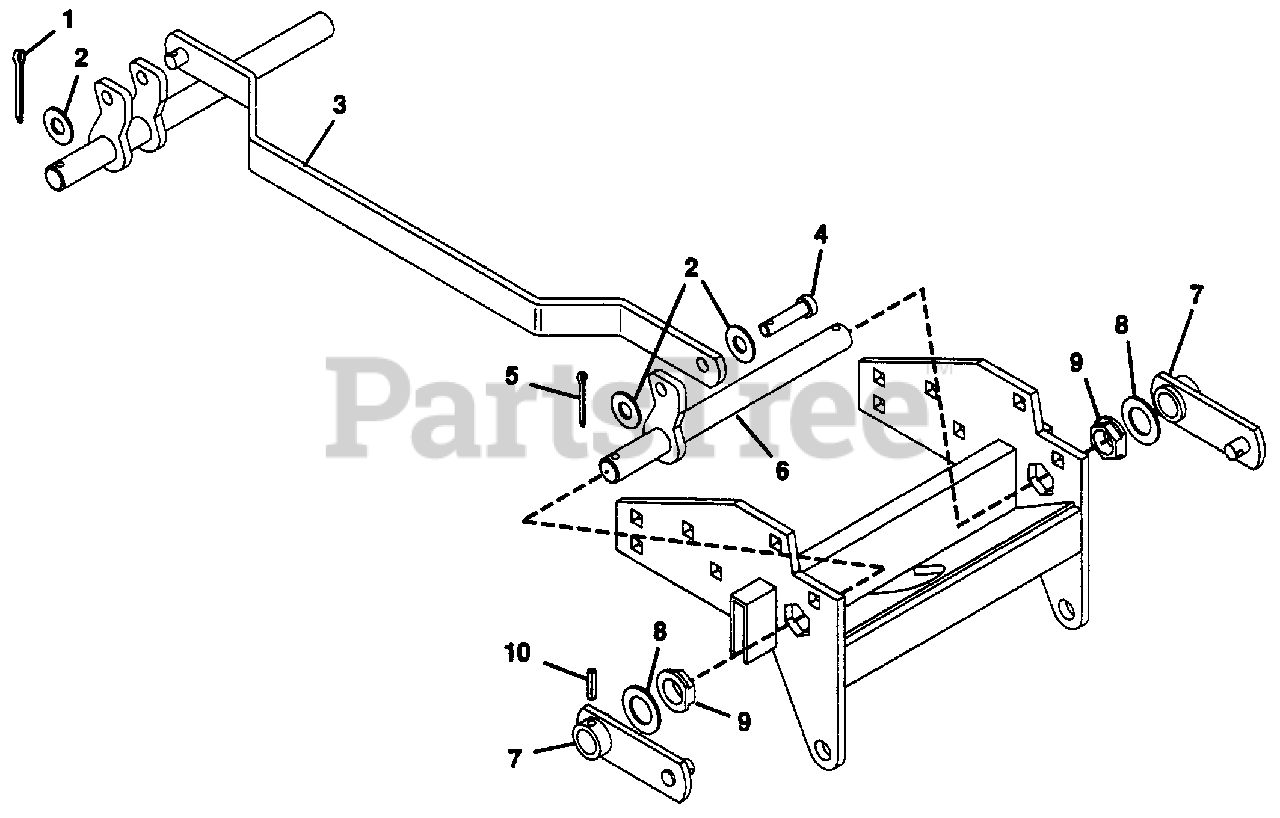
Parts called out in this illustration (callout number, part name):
1	Pin, Cotter .187x1.25
2	Washer, Flat .531x1.250x.100
3	Weldment, Lift Link
4	Pin, Clevis .50x.875
5	Pin, Cotter .125x1.00
6	Pivot, Front
7	Arm, Front Lift
8	Bearing, Thrust Race
9	Bush., Flg. 1.00x1.25x.375 Stl.
10	Pin, Spring .250x1.50
